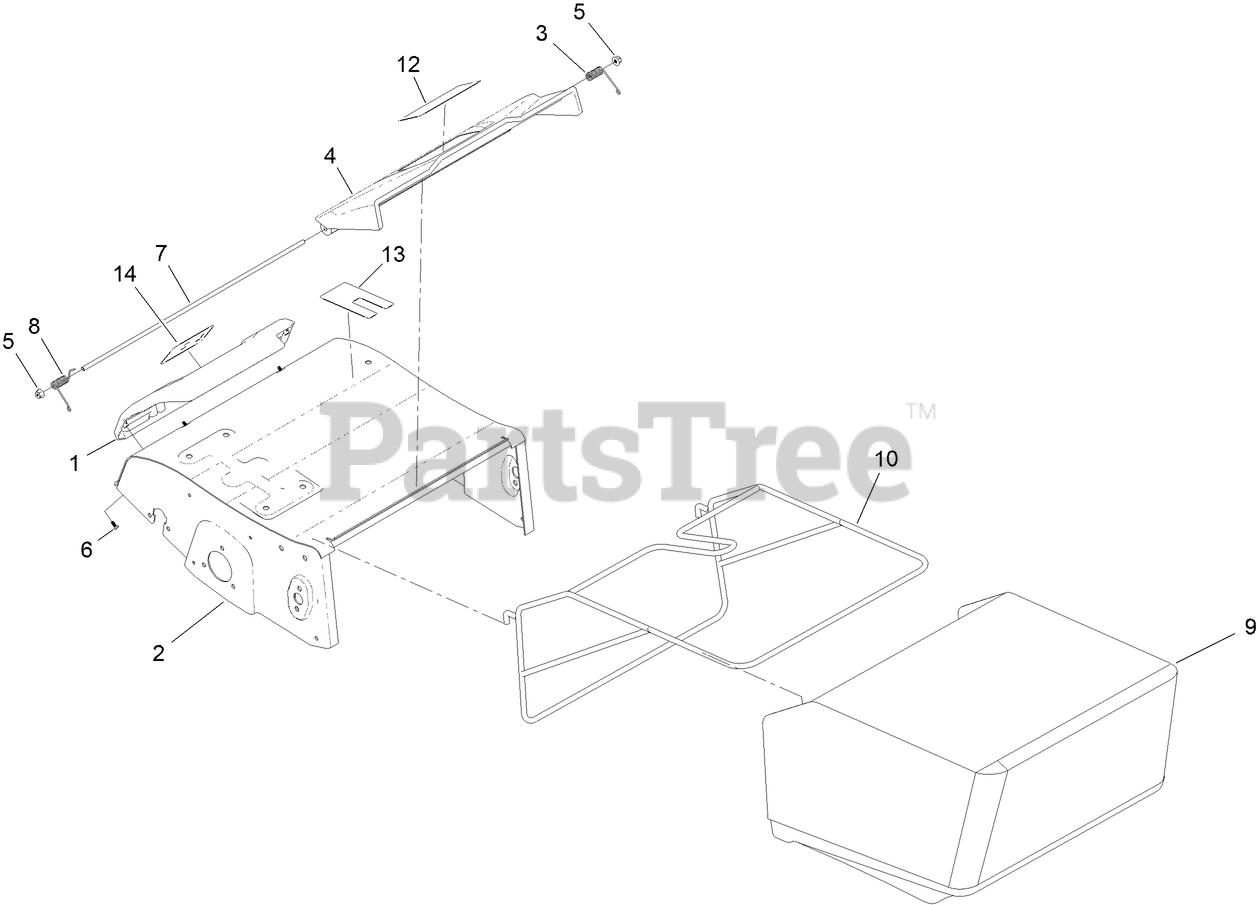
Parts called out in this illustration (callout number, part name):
1	FRONT COWLING
2	DECK HD
3	SPRING-FLAP, REAR RHS
4	FLAP-REAR
5	NUT-LOCK, FLANGE
6	SCREW-PAN HEAD
7	ROD-FLAP
8	SPRING-FLAP, REAR LHS
9	GRASS BAG - FABRIC ASSY
10	GRASS BAG STEEL FRAME
12	DECAL - SAFETY
13	DECAL - DUAL HOC / SPRING TINE
14	DECAL - LOGO TORO
